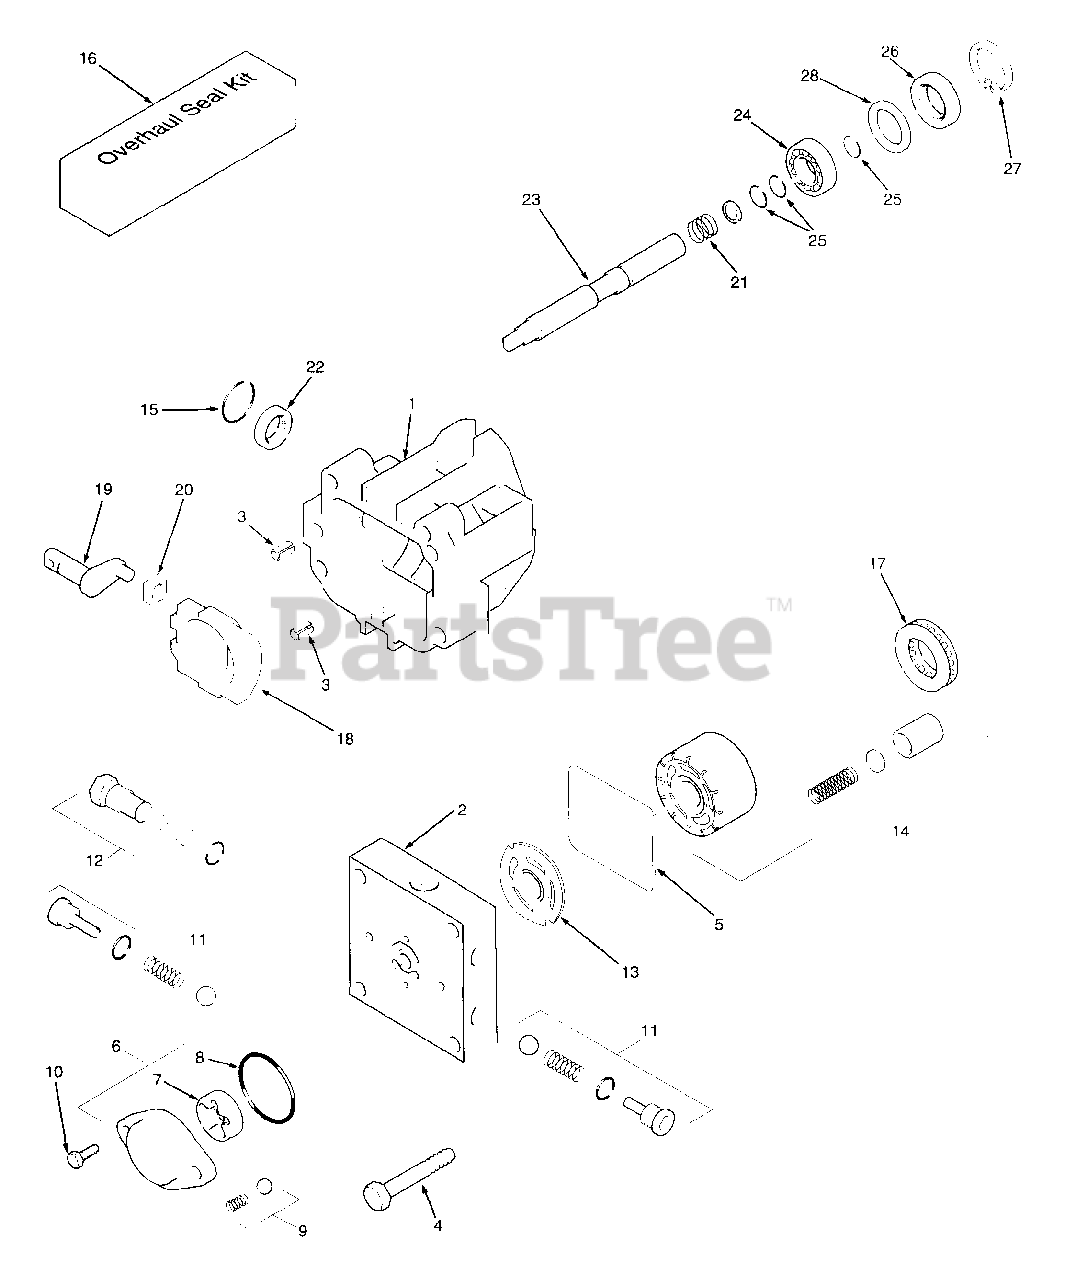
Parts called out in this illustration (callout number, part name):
1	Housing Kit
2	End Cap
3	Straight Headless Pin
4	Socket Head Screw
5	End Cap Gasket
6	Charge Pump Kit
7	Gerotor Assembly
9	Charge Relief Valve Kit
10	Socket Head Screw
11	Check Valve Kit
12	Bypass Valve Kit
13	Valve Plate
14	Cylinder Block Kit
15	Trunion Seal Retaining Ring
16	Overhaul Kit
17	Roller Thrust Bearing
18	Swash Plate
19	Trunnion Arm
20	Guide Slot
21	Block Spring
22	Lip Seal
23	Pump Shaft
24	Ball Bearing
25	Retaining Ring
26	Lip Seal
27	Retaining Ring
